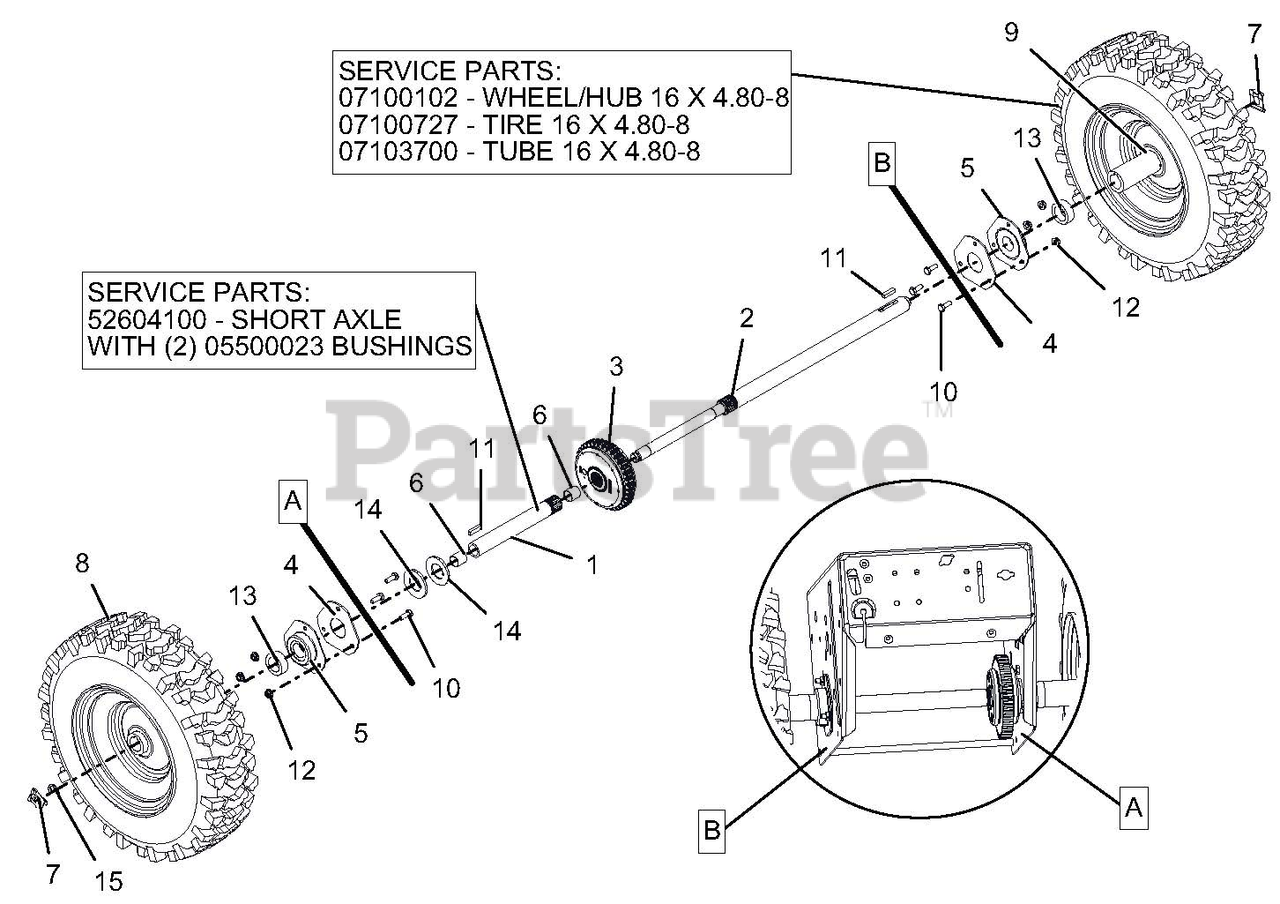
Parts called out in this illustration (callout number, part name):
1	AXLE, SHORT-PRO AUTO DIFF
1	AXLE, SHORT-AUTO W/BUSHINGS
1	BSHG-SLV .706X.764X.75 BRZ
2	AXLE, LONG-PRO AUTO DIFF
3	DIFFERENTIAL, AUTOMATIC
4	PLATE, BEARING SPACER
5	BRG-FLG 1.003/1.000 3 BOLT
6	BSHG-SLV .706X.764X.75 BRZ
7	CLIP, SNAP .625 DIA
8	TIRE/WHEEL,RH 16X4.8-8 DIFF T2
9	TIRE/WHEEL,LH 16X4.8-8 DIFF T2
9	HUB, WHEEL - 16X4.8-8 DIFF
9	TIRE, 4.80-8 K478
9	TUBE
10	@BLT-HEX .25-20X.75 GR5 YWZC
11	KEY-RECT .25X.188X1.00
12	@NUT-LK-CTR-FLG .25-20 YWZC
13	SPACER, PRO AXLE BEARING
14	WSHR-FL-STL- 1.062X2.0X.134 YZ
15	RG-RTNG-EXT .625X.042
